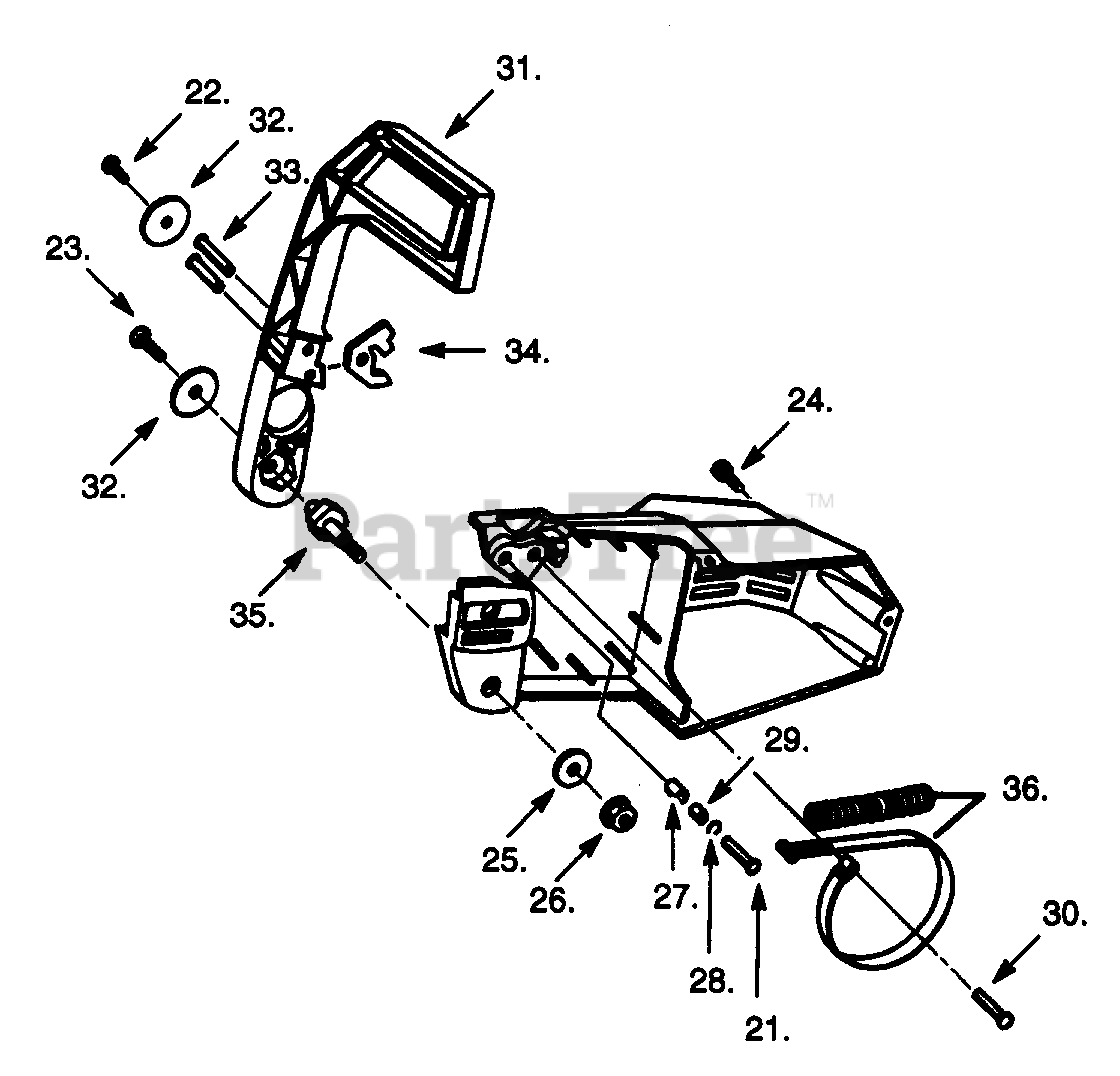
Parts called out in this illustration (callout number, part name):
21	Latch Pin
26	Bar Mounting Nut
27	Latch Roller
30	Anchor Pin
31	Lever
33	Handguard Pin
35	Handguard Pivot
36	Brake Band
